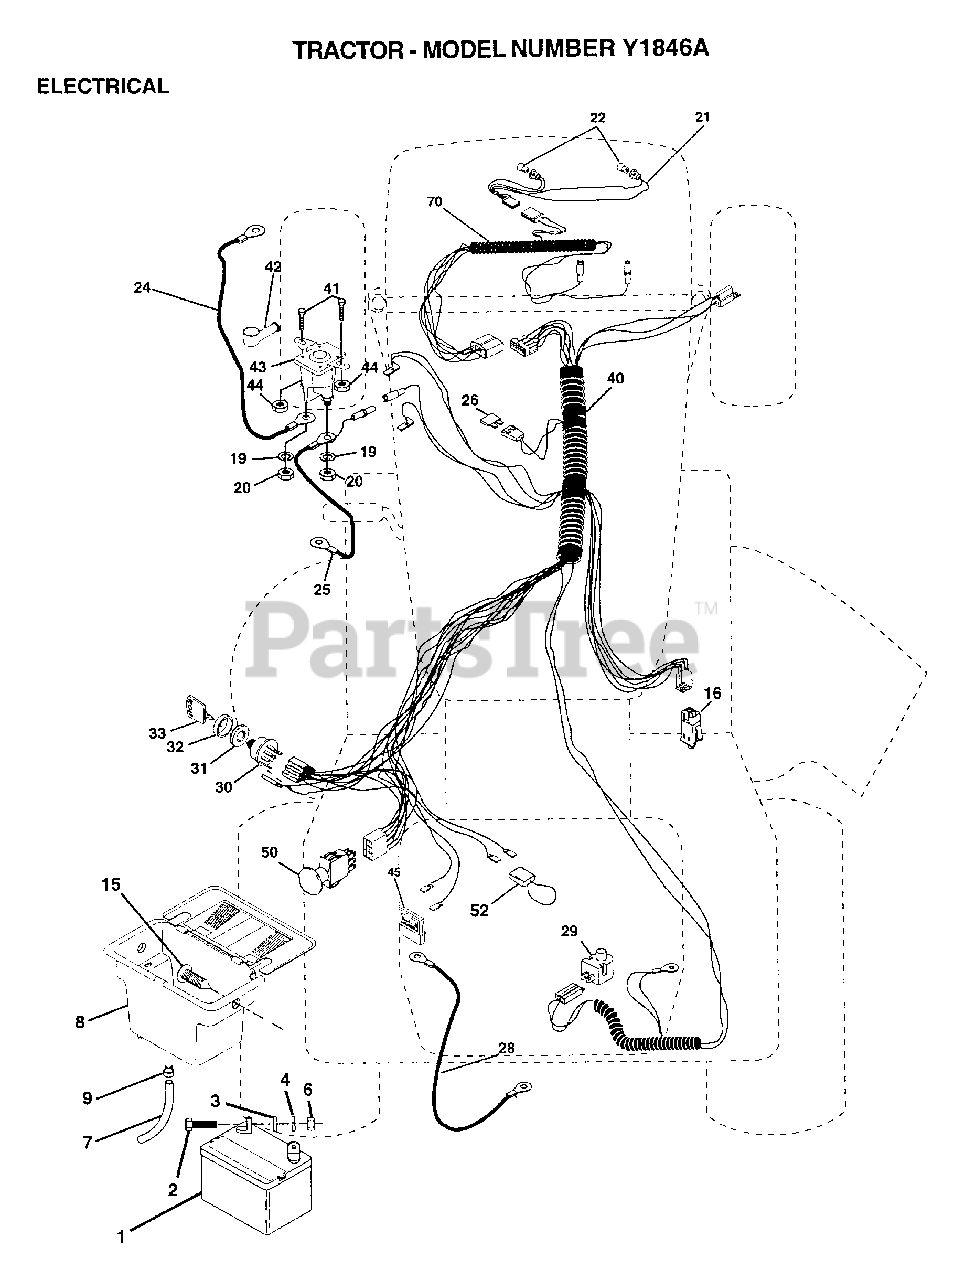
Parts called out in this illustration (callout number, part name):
2	BOLT LT
3	WASHER
4	LOCKWASHER
7	TUBE T
9	HOSE CLAMP T
15	FASTNER.SNAP-IN
16	SWITCH INTERLOCK
20	NUT
21	"HARNESS,LIGHT SOC"
22	HEADLAMP BULB
24	CABLE-BATTERY T
25	CABLE.BTRY.6GA.RD
26	FUSE HYT
28	CABLE T
29	SWITCH SEAT
30	SWITCH IGN 4POS
31	NUT IGNITION
32	COVER KEY SWITCH
33	KEY
40	IGNITION HARNESS
41	BOLT HXHD FIN
44	NUT HXKEP 1/4X20
45	AMMETER
52	PROTECTION LOOP
70	HARNESS.ENG.PL/LT
